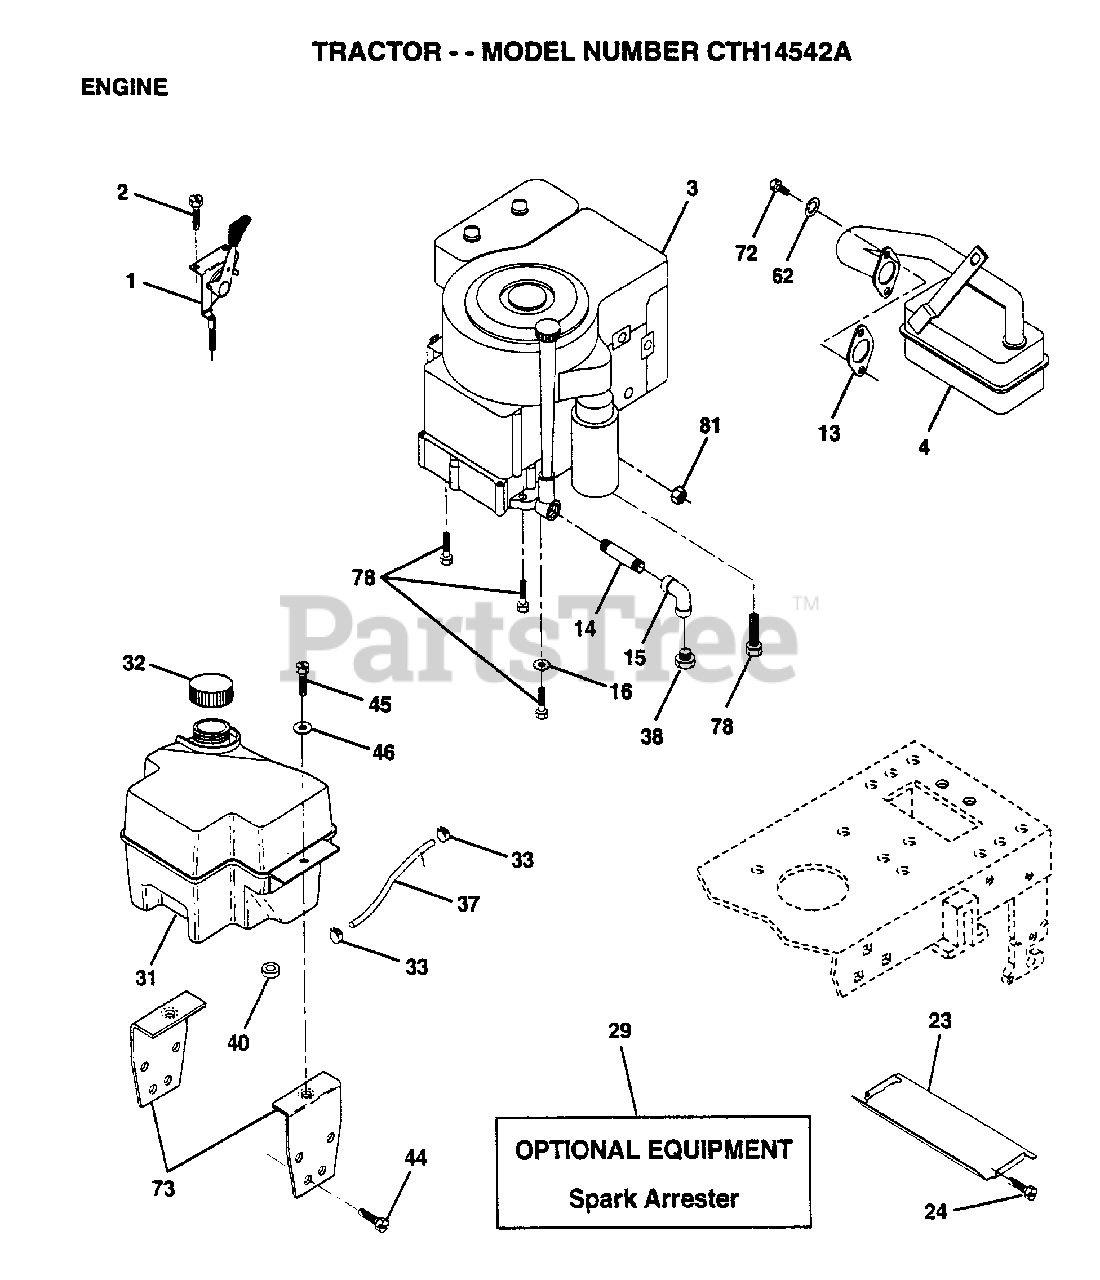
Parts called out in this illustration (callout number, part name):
1	CONTROL.THTL.19.6
2	SCREW LT
4	MUFFLER
14	PIPE NIPPLE
15	ELBOW
16	LOCKWASHER
23	HEAT SHIELD
32	CAP ASM FUEL
33	HOSE CLAMP
37	LINE FUEL
44	SCREW
45	SCREW HEX CRT
46	WASHER
62	LOCKWASHER
72	SCREW
73	BRACKET.SUPT.TANK
78	SCREW
81	NUT
